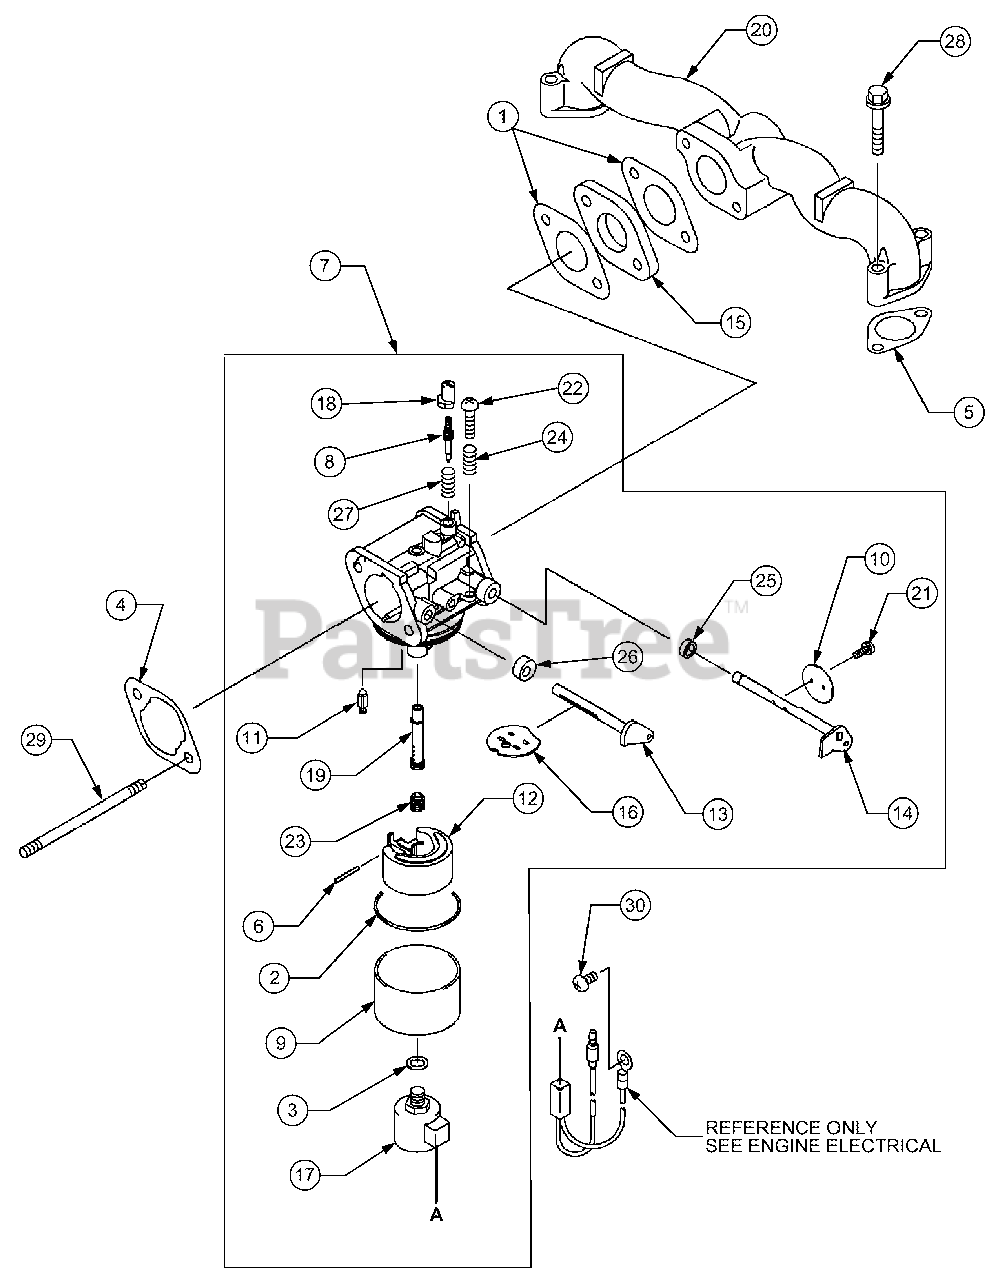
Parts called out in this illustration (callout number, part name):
1	Gasket, Insulator
2	Gasket, Chamber
4	Gasket, Air Cleaner
7	Carburetor Assy
8	Screw, Pilot Air
9	Chamber, Float
10	Valve, Throttle
13	Shaft, Carburetor Choke
14	Shaft, Carburetor Throttle
15	Insulator
20	Manifold, Intake
23	Jet, Main, #105
28	Bolt, Flanged
